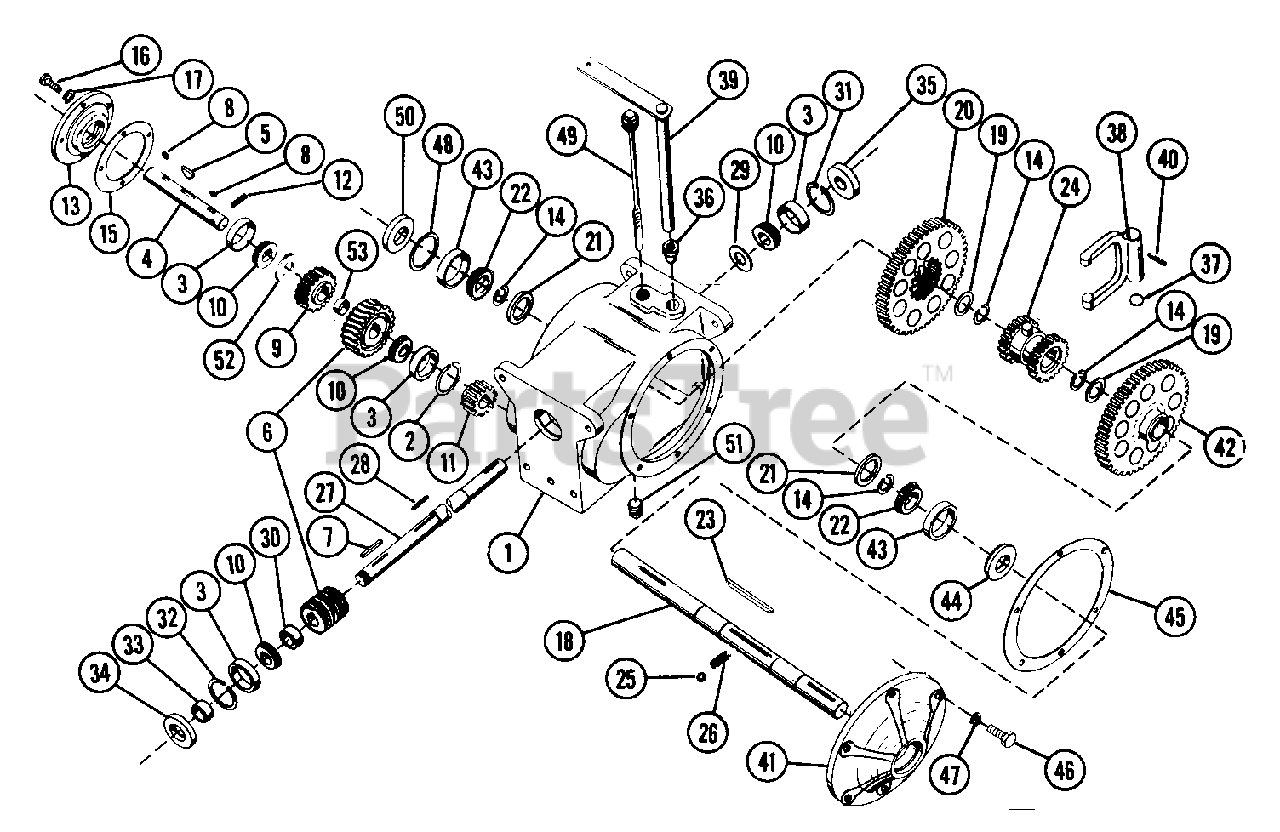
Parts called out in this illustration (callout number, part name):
1	TRANSMISSION CASE
2	RG-RTNG-INT 1.781X.062
3	BRG-CUP 1.781X.475
4	PINION SHAFT
5	KEY-WDRF .188X.875X.375 SAE11
6	50100& WORM GEAR ASSEMBLY TRAN
7	KEY-WDRF .188X.625X.31 SAE9MOD
8	KEY-WDRF .188X.75X.313 SAE 9
9	HIGH PINION
10	BRG-CONE .750X.61
11	LOW PINION
12	PIN-ROLL .188X1.00
13	PINION FLANGE
14	RG-RTNG-EXT .984X.062
16	BLT-HEX .31-18X.75 PL GR2
17	WSHR-LK .312X.097 PL HVY
18	AXLE SHAFT
20	HIGH GEAR ASSEMBLY
21	GEAR SPACER 1.75 X 1.31 X .5
22	BRG-CONE 1.0X.58
23	KEY-FTHR .25X2.75X.25 SAE1035
24	CLUTCH HUB
25	STEEL BALL
26	SG-COMP .047X.31X.593 WLD11
27	WORM SHAFT
28	KEY-SQ .188X1.0X.188 SAE 8630
29	WSHR-FL-STL .755X1.375X.125
30	BSHG, SPCR .755X1.12X.50 PM
31	RG-RTNG-INT 1.781X.052
32	SNAP RING KIT
33	SPACER BUSHING .99 X .75 X .50
34	SEAL 1.000X1.785X.250
35	SEAL .750X1.781X.250
36	BSHG-FLG .625X.813X.750
37	SPACER DISC (USE SCRAP MATRL)
38	SHIFT YOKE
39	HIGH-LOW SHIFT LEVER
40	PIN-ROLL .250X1.00
41	TRANSMISSION FLANGE
42	LOW GEAR
43	BRG-CUP1.980X.420
44	SEAL 1.000X1.785X.250
45	WHEEL GASKET
46	BLT-HEX .31-18X.88 PL GR2
47	WSHR-LK .312X.097 PL HVY
48	SNAP RING KIT
49	DIP STICK
50	SEAL 1.000X1.980X.250
51	PIPE PLUG
52	LOAD RING
53	SPACER 1.25 X .75 X .75
